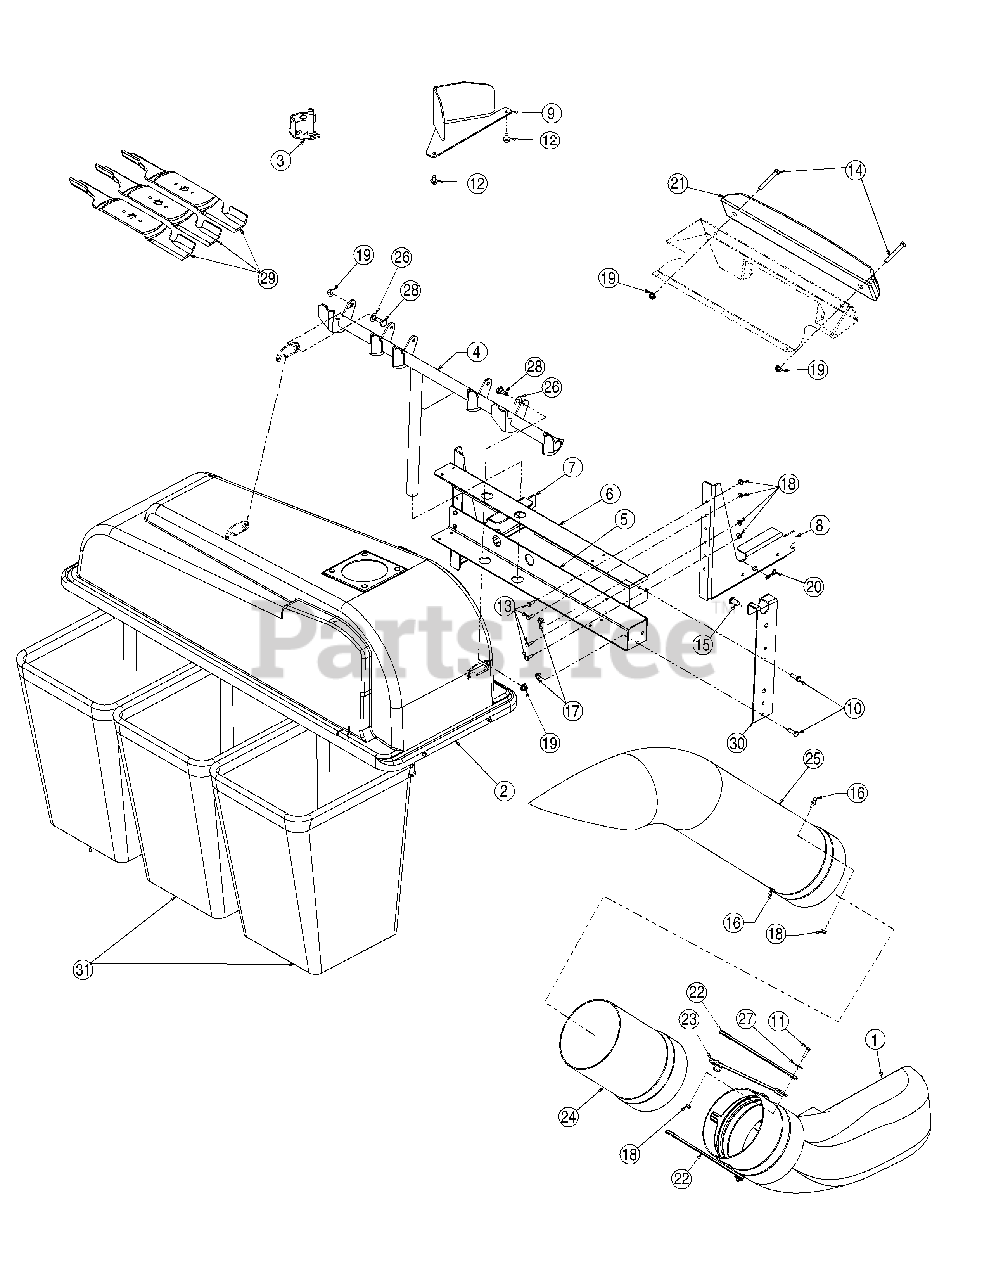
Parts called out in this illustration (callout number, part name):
2	Grasscatcher Cover Assembly
10	Screw, Hex Cap, 5/16-18 x 1.0 Gr5
11	Screw, Hex Cap, 1/4-20 x 1.0 Gr5
12	Screw, Hex Wash. Hd. TT, 5/16-18 x 0.625
13	Screw, Hex Cap, 1/4-20 x 0.75 Gr5
14	Screw, Hex Cap, 3/8-16 x 2.75 Gr5
15	Pin, Clevis , .5 x .78
16	Pin, Grasscatcher 1/4-20
17	Nut, Hex Flange Insert Lock, 5/16-18
18	Nut, Hex Flange Insert Lock,1/4-20
19	Nut, Hex Flange Insert Lock, 3/8-16
20	Pin, Internal Cotter
21	Weight, Bagger
24	Tube, Extension, 8"
25	Tube, Catcher
26	Washer, Bell, .525 x 1.0 x .05
27	Washer, Flat, .265 x 1.0 x .03 HT
28	Shoulder Screw, .5 x .270: 3/8-16
29	Blade
31	Bag Assembly, Catcher
